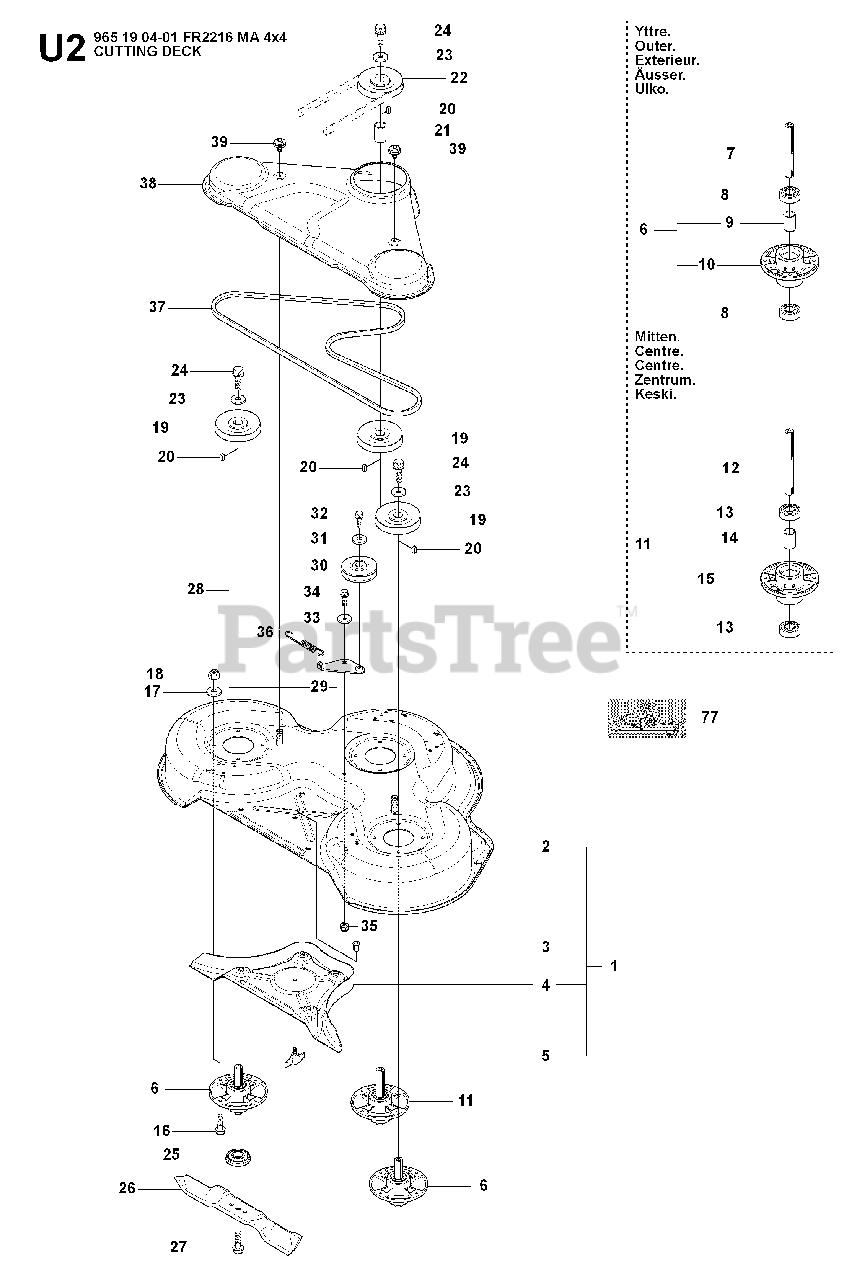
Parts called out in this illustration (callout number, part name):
6	RP SPINDLE ASSY
10	BEARING HOUSING
15	BEARING HOUSING
17	WASHER BRB 8.4X17
18	LOCKNUT M8
30	PULLEY
33	WASHER
35	LOCKNUT M8
